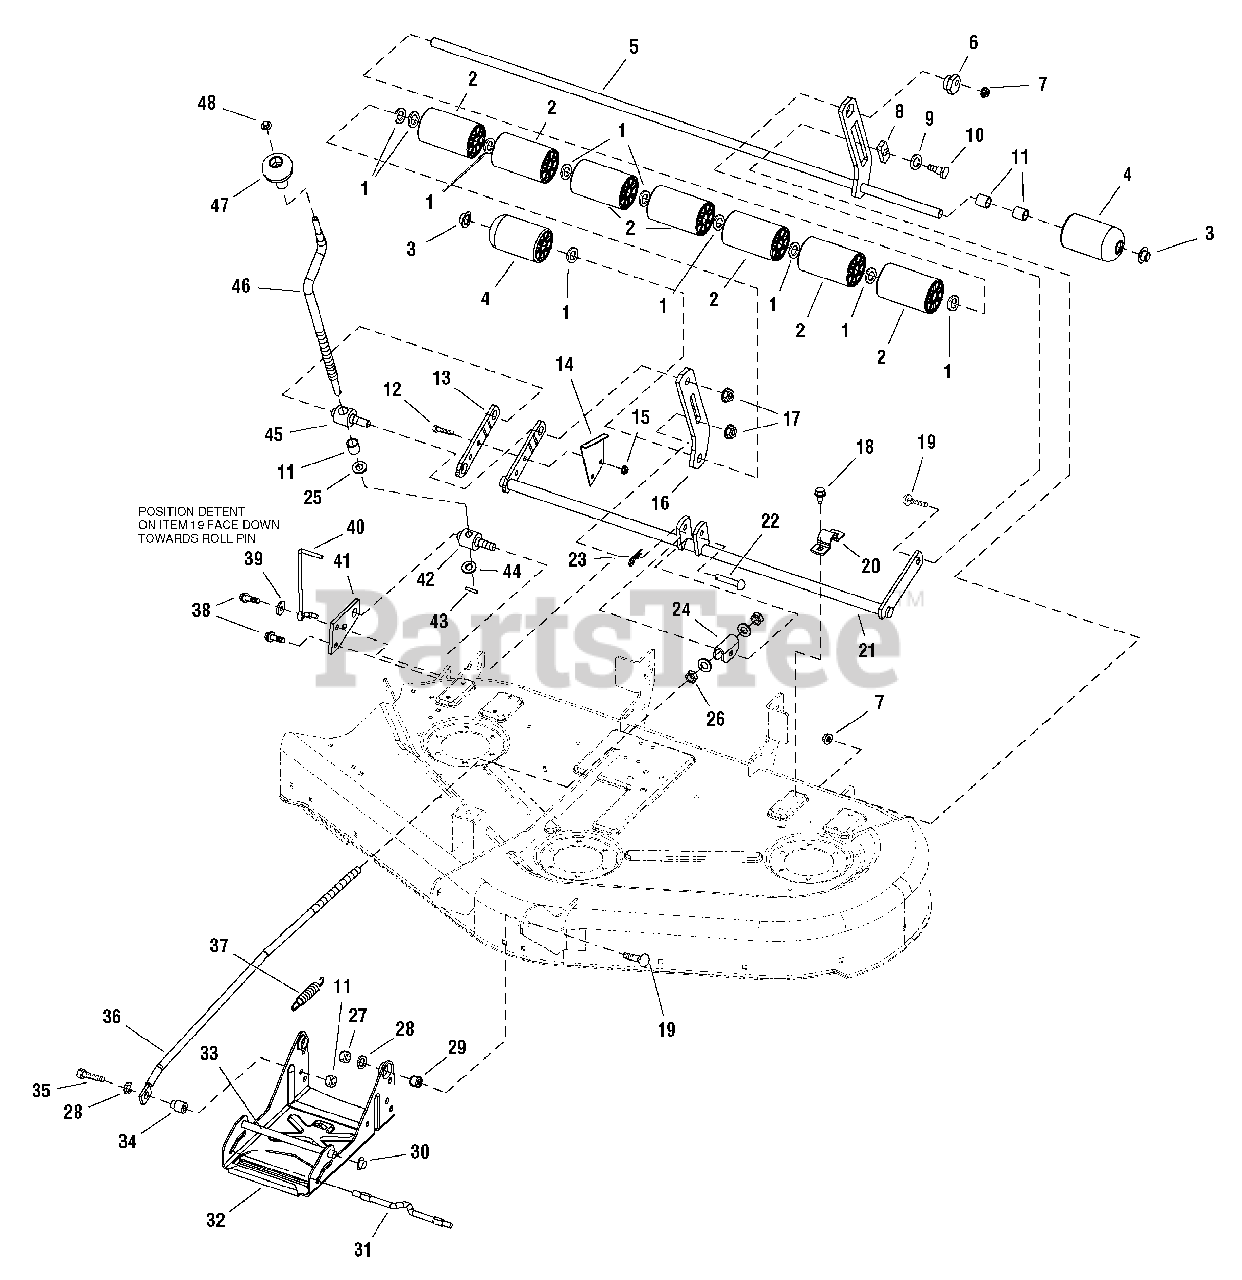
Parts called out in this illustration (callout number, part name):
1	WASHER, 5/8
2	ROLLER
3	PUSH NUT, 5/8
4	ROLLER, Rounded End
5	SHAFT ASSEMBLY, Roller 44"
6	NUT, Adjuster
7	NUT, Hex Toplock Spiral Flange, 3/8-16
8	SLIDE
9	WASHER, Plain
10	SHOULDER BOLT
11	SPACER
12	CAPSCREW, Hex Head, 5/16-18 x 1-1/4
13	ARM, Rear Mower, RH
14	BRACKET, Cutting Height
15	NUT, 5/16-18, Hex NC-2B
16	BAR, Roller 44"
16	BAR, Roller 44" & 50"
17	NUT, Hex Head, 1/2-13
18	CAPSCREW, Hex Head, Taptite, 5/16-18 x 3/4
19	CARRIAGE BOLT, 3/8-16 x 1-1/2
20	STRAP
21	SHAFT ASSEMBLY, Rocker 44"
22	PIN
23	CLIP, Spring
24	TRUNNION
25	WASHER, 1/2
26	LOCKNUT, Hex, Jam, 1/2-13
27	NUT, Hex, 3/8-16 ESNA Lock
28	WASHER, 3/8
29	SPACER
30	NUT, Push, 1/2
31	ROD
32	SUPPORT, Mower
33	ROD
34	SPACER, 3/8 x 3/4 x 15/16
35	CAPSCREW, Hex Head, 3/8-16 x 1 3/4
36	ROD, E-Coat, 1/2-13 x 5.3, 28.900LG
37	SPRING, Extension
38	CAPSCREW, Taptite, 5/16-18 x 1-1/4
39	WASHER, Plain, 5/16
40	ROD, Indicator Cutting Height
41	PLATE, Mower Support
42	TRUNNION
43	PIN, Spring
44	WASHER, Detent
45	TRUNNION, Threaded
46	CRANK, Height Adjustment, Black
47	KNOB, Chute Control Spinner
48	NUT, Push, 3/8
